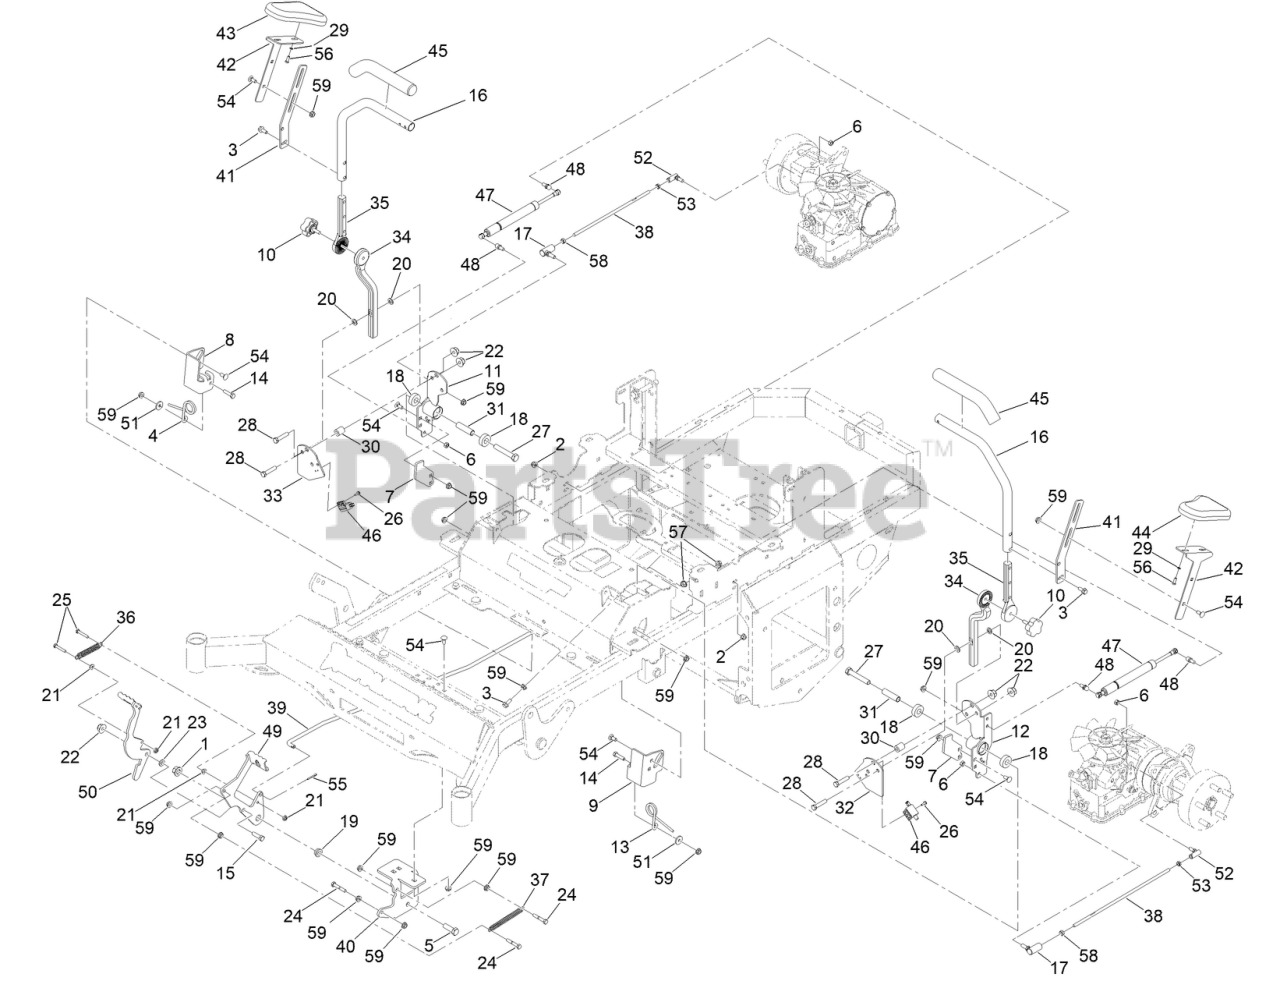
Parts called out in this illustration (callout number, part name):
1	NUT-LOCK
2	NUT-HF, NI
3	SCREW-HHF
4	SPRING-TORSION
5	SCREW-HH
6	5/16-24 NYL INS L/N GR.8 ZC/YEL
7	REVERSE DETENT KICK PLATE
8	REVERSE DENTENT SPRING BASE (RH)
9	REVERSE DENTENT SPRING BASE (LH)
10	5/16-18 X 1 SL 5-LOBE MALE ST KNOB 1.90
11	MOTION CONTROL BRKT
12	MOTION CONTROL BRKT
13	SPRING- LT REVERSE DETENT
14	SCREW-HH
15	SCREW-HH
16	MOWER DRIVE HANDLE TUBE ABC
17	CONTROL ARM ROD END LT
18	5/8IN ID X 1-3/8IN OD X 7/16IN THK BRG
19	1/2IN ID X 3/4IN OD X 3/8IN FLANGE BUSH
20	3/8 X 3/4 BRONZE WASHER
21	1/4-20 HEX FLANGE NUT
22	3/8-16 NYLON INSERT FLANGE L/NUT YZ
23	3/8 ID X 3/4 OD X .125 THK BRONZE WASHER
25	1/4-20 X 1-1/4 HEX C/S GR 2 ZINC
26	8-32 X 1/2 IND. HWH SLOT TYPE F TCS ZINC
27	1/2-13 X 3 HEX C/S GR 5 ZINC W/LOCTITE
28	3/8-16 X 1-3/4 HEX C/S GR 2 ZINC
29	1/4 EXT TOOTH LOCKWASHER ZINC
30	MWR DRIVE ARM SPACER
31	MWR DRIVE ARM HUB / DECK LIFT ARM SPACER
32	LT CONTROL ARM LIMIT SWITCH PLATE PAINT
33	RT CONTROL ARM LIMIT SWITCH PLATE PAINT
34	ADJUSTABLE LWR DRIVE ARM
35	ADJUSTABLE UPP DRIVE ARM
36	MWR BRAKE PEDAL RELEASE SPRING
37	2020 MWR BRAKE PEDAL TENSION SPRING
38	TRANS DRIVE ARM LINKAGE STANDARD TRANS
39	MWR BRAKE LINKAGE
40	MWR FRAME BRAKE MTG BRKT PAINT
41	MWR ARM PAD TUBE MTG BRKT PAINTED
42	MWR ARM PAD MTG BRKT PAINTED
43	2020 MWR DRIVE ARM SUPPORT PAD LT
44	2020 MWR DRIVE ARM SUPPORT PAD RT
45	CONTROL ARM HANDLE GRIP
46	NO PLUNGER LIMIT SWITCH
47	CONTROL ARM DAMPER
48	5/16-18X1.286 DAMPER BALL STUD (.562 TL)
49	MWR BRAKE LOCK LEVER ASSY PAINTED
50	MWR BRAKE UNLOCK LEVER ASSY PAINTED
51	STRIKER POST FENDER WASHER
52	BALLJOINT-RH (W/GROMMET)
53	NUT-JAM
54	BOLT-CARR
55	PIN-COTTER
56	SCREW-HSBH
57	3/8-16 HEX FLANGE NUT W/SERR ZINC YELLOW
